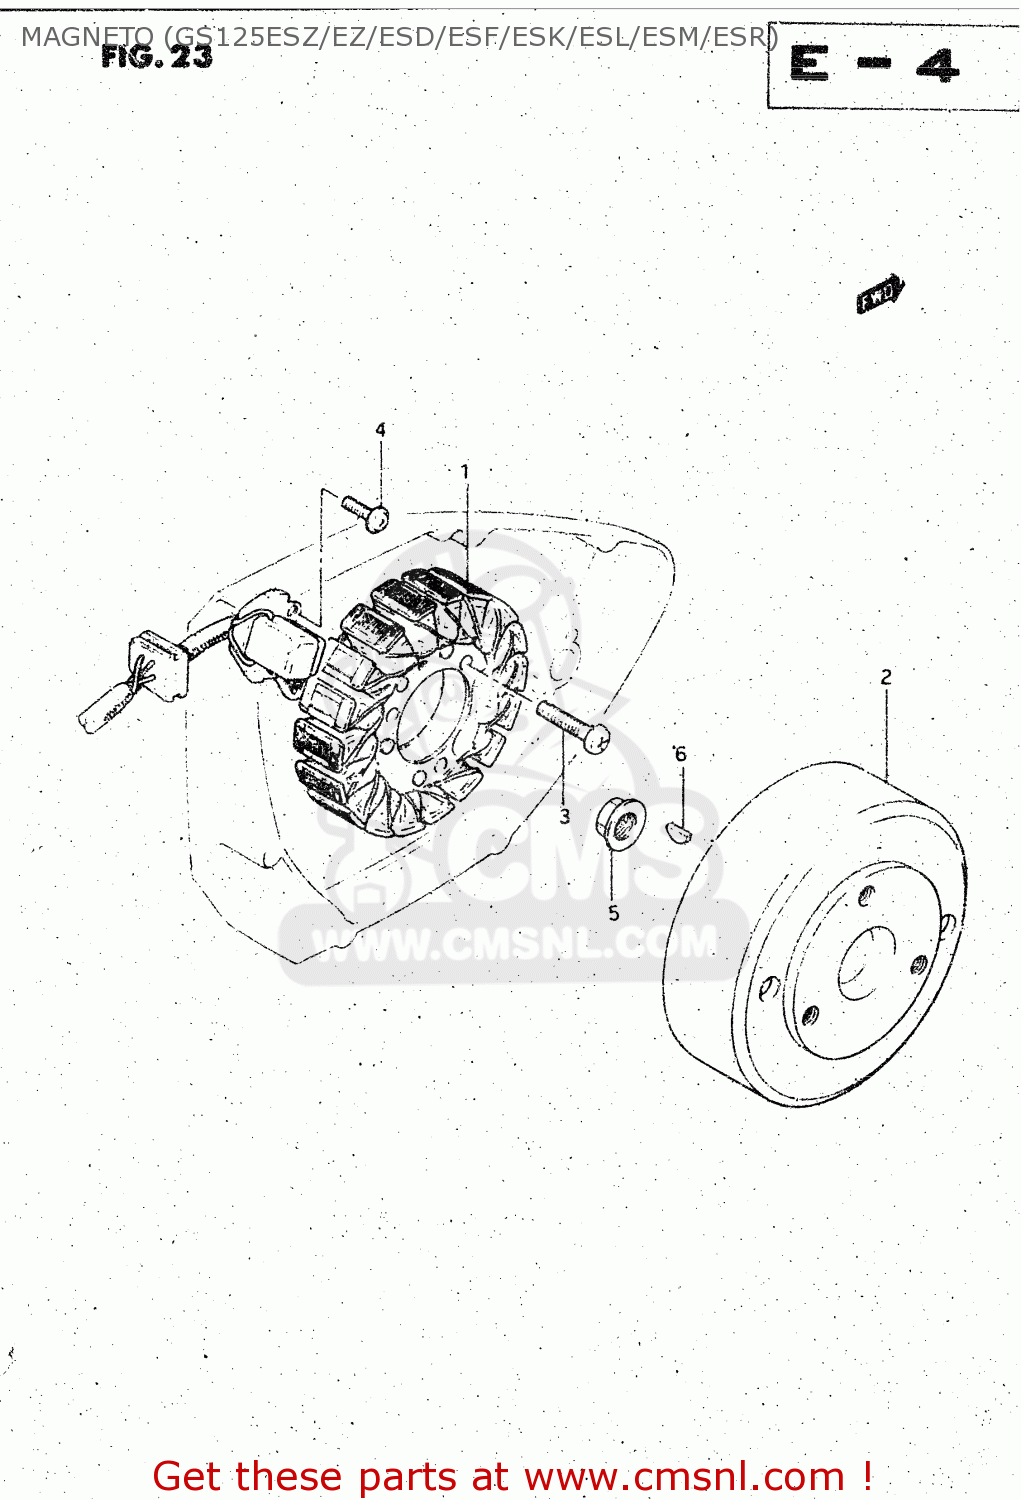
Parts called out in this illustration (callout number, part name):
1	STARTER ASSY
2	ROTOR,FLYWHEEL
3	SCREW
4	SCREW
5	NUT
6	KEY
